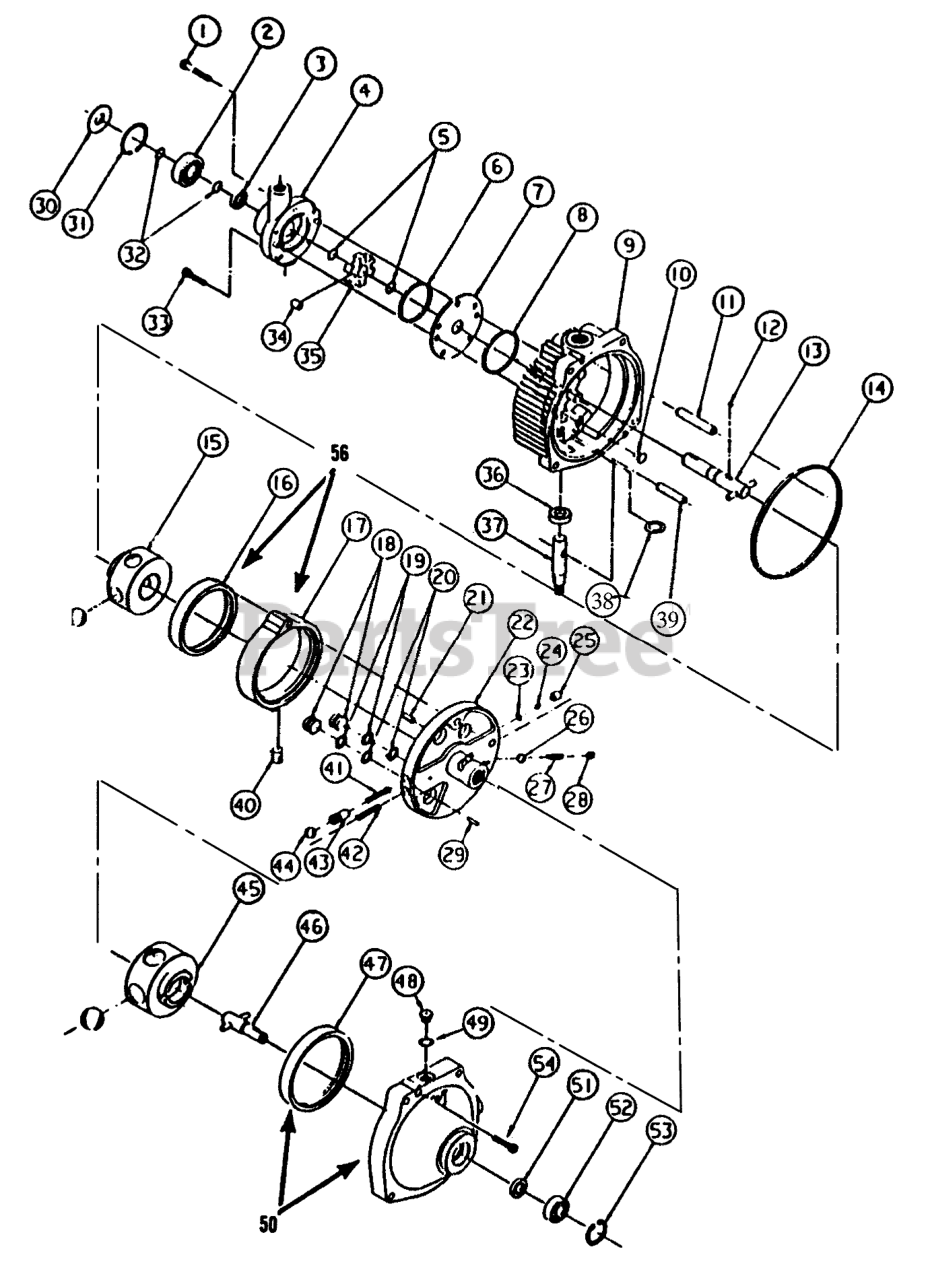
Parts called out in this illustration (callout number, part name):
1	Screw
2	Bearing-Input
3	Seal
4	Housing-Pump Assembly (Incl. Ref. #2)
5	Ring
6	Ring-Seal
7	Plate
8	Ring-Seal
9	Cover Assembly (Incl. Ref. #3, 6, 8, 10, 11, 19, 20, 36-39, & 51)
10	Button
11	Pin-Pivot
12	Pin
13	Shaft-Input
14	Ring-Seal
15	Rotor-Pump
16	PUMP-RACE
17	Ring-Cam
18	Piston
19	Ring-Back Up
20	"O"Ring
21	Pin-Coil
22	Pintle Assembly (Inc. Ref. #21, 23-29 & 41-44)
23	Ring-Retaining
24	Ball
25	Body-Check Valve
26	Ball
27	Spring-Relief Valve
28	Plug-Relief Valve
29	Pin
30	SHIELD-GRASS
31	RETAINING-RING
32	Ring
33	Screw
34	Roller
35	Carrier
36	Seal
37	Kit-Control
38	Washer
39	Dowel
40	Insert-Cam Ring
41	Spring-Acc. Valve
42	Spring-Acc. Valve
43	Body-Acc. Valve
44	Ball
45	Rotor-Motor
46	Shaft-Output
47	Race-Motor
48	Plug-"O"Ring (Incl. Ref. #49)
49	O-Ring
50	Body Assembly (Incl. Ref. #51, 53 & 54)
51	Seal ASM
52	Bearing-Output
53	Retaining Ring
54	Screw
55	Kit-Seal, Overhaul (Incl. Ref. #3, 6, 8, 14, 19, 20, 36, 49 & 51)
56	Ring-Cam
